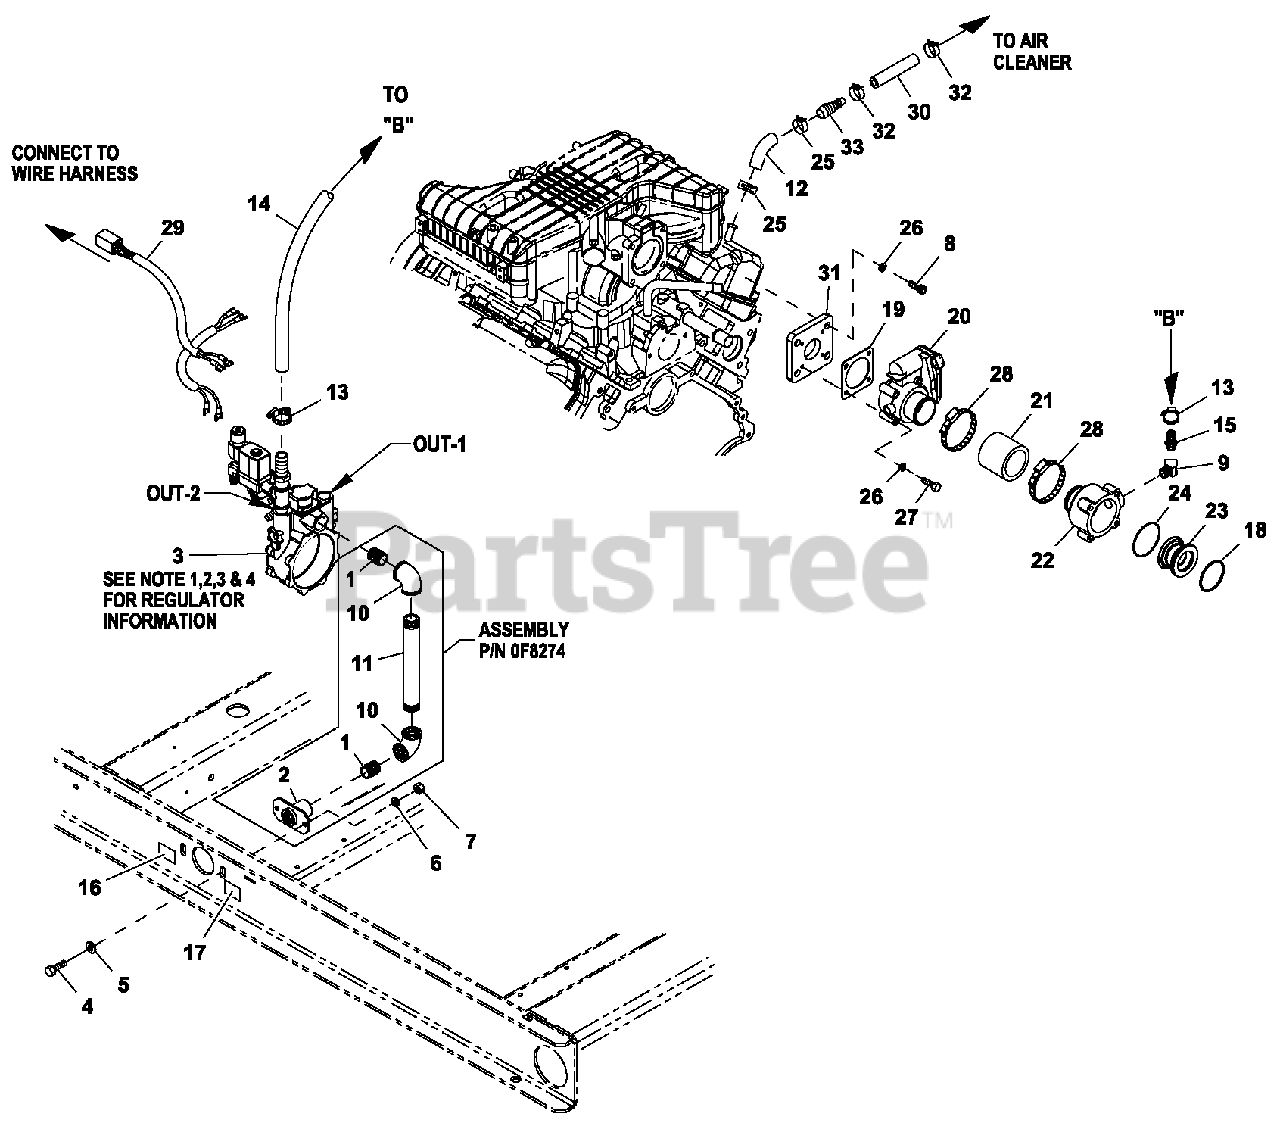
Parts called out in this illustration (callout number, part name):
1	NIPPLE CLOSE 3/4X1.375
2	FLANGE FUEL INLET
3	REGULATOR ASSY 4.2L 48KW
4	SCREW H H C M8-1.25 X 20 G8.8
5	WAS H ER FLAT 5/16-M8 ZINC
6	WAS H ER LOCK M8-5/16
7	NUT H EX M8-1.25 G8 CLEAR ZINC
8	SCREWS H C M6-1.0X 18 G12.9
9	STREET EL 45D 1/2 NPT BRASS
10	ELBOW 90D 3/4 NPT
11	NIPPLE PIPE 3/4 NPT X 7
12	H OSE COOL 5/8"ID 250#WP (2"LG)
13	CLAMP H OSE #10.56-1.06
14	H OSE 3/4 ID LPG & NG (22" LG)
15	BARBED STR 1/2 NPT X 3/4
16	DECAL INLET PRESSURE
17	DECAL FUEL INLET
18	O-RING 45.63 ID X 2.62 WIDT H
19	GASKET BOSCH 32
20	ACTUATOR BOSC H 40 GOVERNOR
21	H OSE COOL 2 IN ID 20R4
22	MIXER ACTUATOR 40MM MAC H INED
23	VENTURI TH ROTTLE 26MM
24	O-RING 47.625 ID X 2.38 WIDT H
25	CLAMP H OSE BAND .88"
26	WAS H ER LOCK M6-1/4
27	SCREWS H C M6-1.0X45 G12.9
28	CLAMP H OSE #28 1.32-2.25
29	HARN FUEL JUMPER SINGLE REG
30	H OSE 3/8 ID SINGLE BRAID (20" LG)
31	INTAKE ADAPTER 4.2L G3-BOSCH
32	CLAMP H OSE BAND .63
33	H OSE BARB REDUCER 5/8"-3/8"ID
